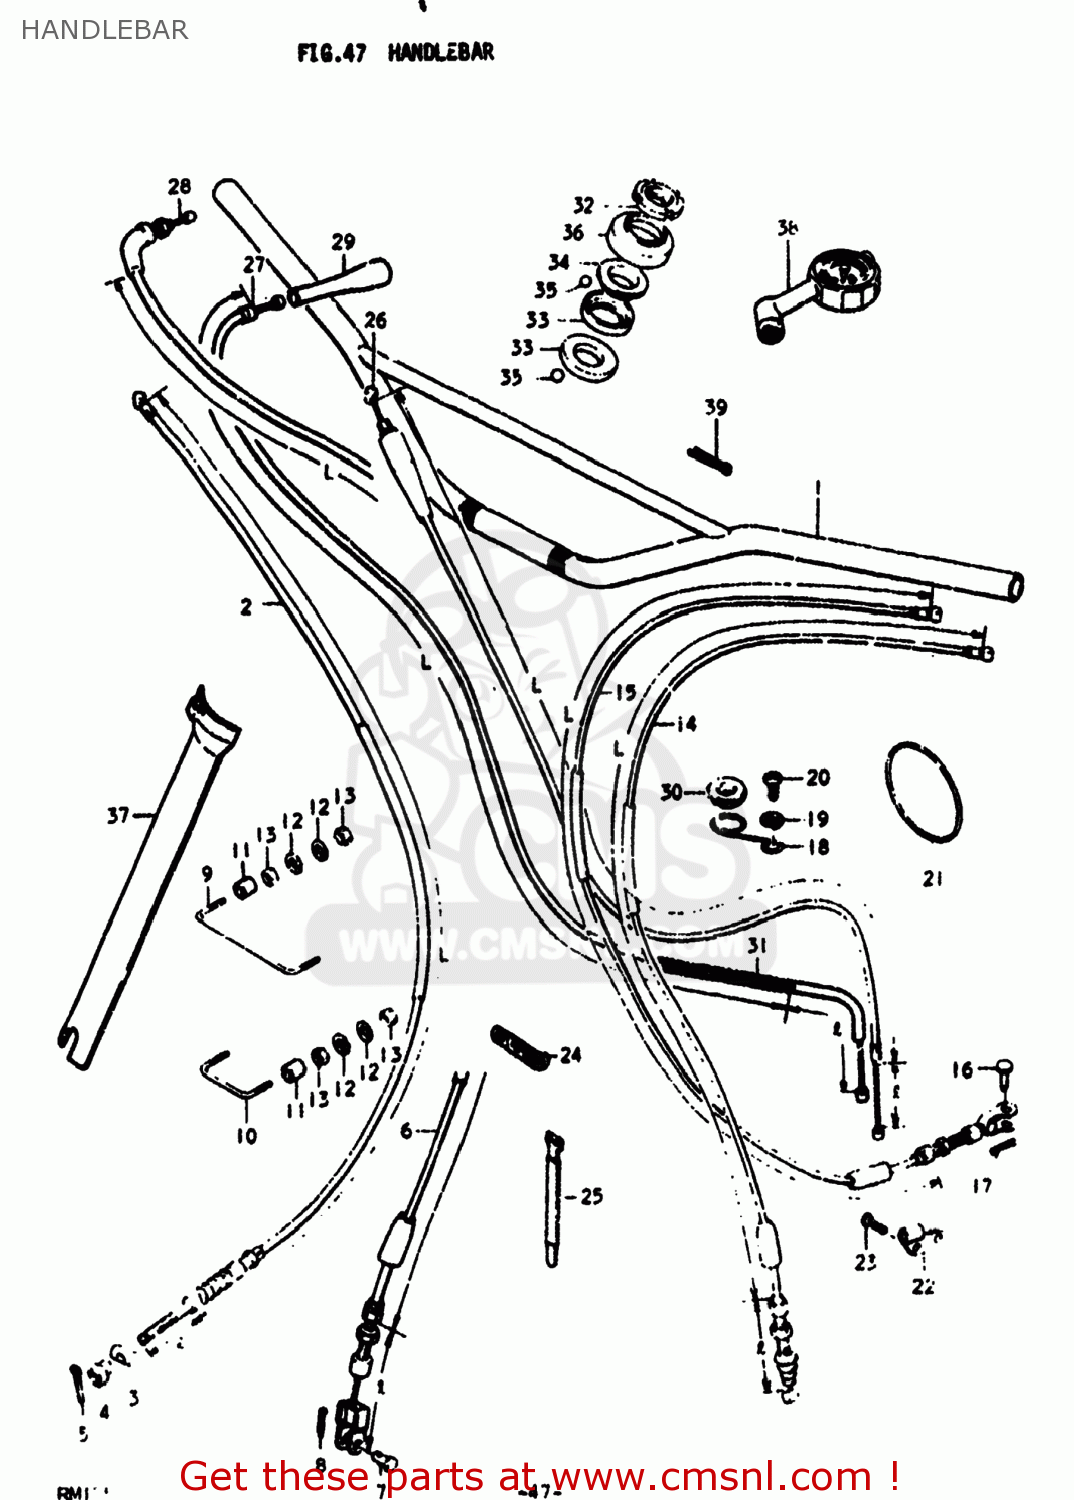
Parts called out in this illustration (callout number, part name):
1	HANDLEBAR
2	CABLE ASSEMBLY,FRONT BRAKE
3	PIN
4	NUT
5	PIN
6	CABLE ASSEMBLY,FRONT BRAKE
7	PIN(L:17.5)
8	PIN
10	CLAMP,CABLE
11	BUSHING
12	WASHER
13	NUT
14	CABLE ASSY,CLUTCH
15	CABLE ASSY,CLUTCH
16	PIN(L:13)
17	PIN
18	CLIP
19	LOCK WASHER
20	SCREW 6X12
21	O RING(D:2.5,ID:68.5)
22	STOPPER,CLUTCH CABLE
23	SCREW
24	CLAMP L:35
25	CLAMP
26	CABLE ASSEMBLY,THROTTLE
27	CABLE ASSEMBLY,THROTTLE
28	CABLE ASSEMBLY,THROTTLE
29	SEAL
30	GROMMET
31	PROTECTOR,CABLE
32	NUT,STEERING STEM(25X44X10)
33	LACE,STEERING INNER LWR
34	LACE,STEERING OUTER UPR
35	BALL
36	DUST SEAL,STEERING UPR
37	PROTECTOR
38	GAUGE ASSEMBLY,AIR PRESSURE
39	COTTER PIN
